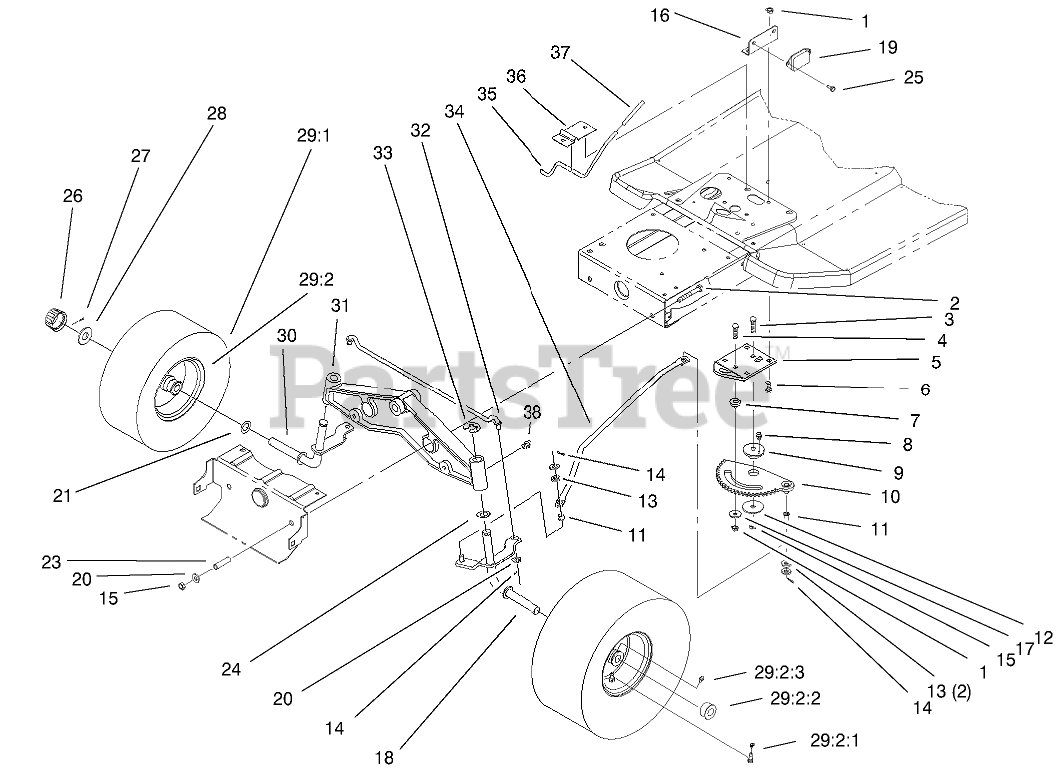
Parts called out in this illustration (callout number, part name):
1	NUT-LOCK, NI
2	SCREW-HH
3	SCREW-CARR
4	SCREW-CARR
5	BRACKET-RACK, STEERING
6	BOLT-CARR
7	SPACER-RACK, STEERING
8	FITTING-GREASE
9	BUSHING-ECCENTRIC
10	RACK-STEERING
11	BUSHING-FLANGED, NYLON
12	WASHER-BEARING
13	WASHER-FLAT
14	PIN-COTTER
15	NUT-LOCK, NI
16	BRACKET-MODULE
17	WASHER-PIVOT
18	LH SPINDLE ASM
19	MODULE
20	WASHER-FLAT
21	WASHER-THRUST
23	SPACER
24	WASHER-THRUST
25	SCREW-HWH
26	CAP-HUB
27	PIN-COTTER
28	WASHER-PLAIN
29:2	RIM ASM
29:2:1	STEM-VALVE
29:2:2	BEARING-WHEEL
29:2:3	FITTING-GREASE
30	RH SPINDLE ASM
31	AXLE-FRONT
32	TIE ROD-STEERING
33	E-RING
34	LINK-DRAG
35	ROD-BRAKE, PARKING
36	BRACKET-PARKING BRAKE
37	GRIP-BRAKE, PARKING
38	FITTING-GREASE
